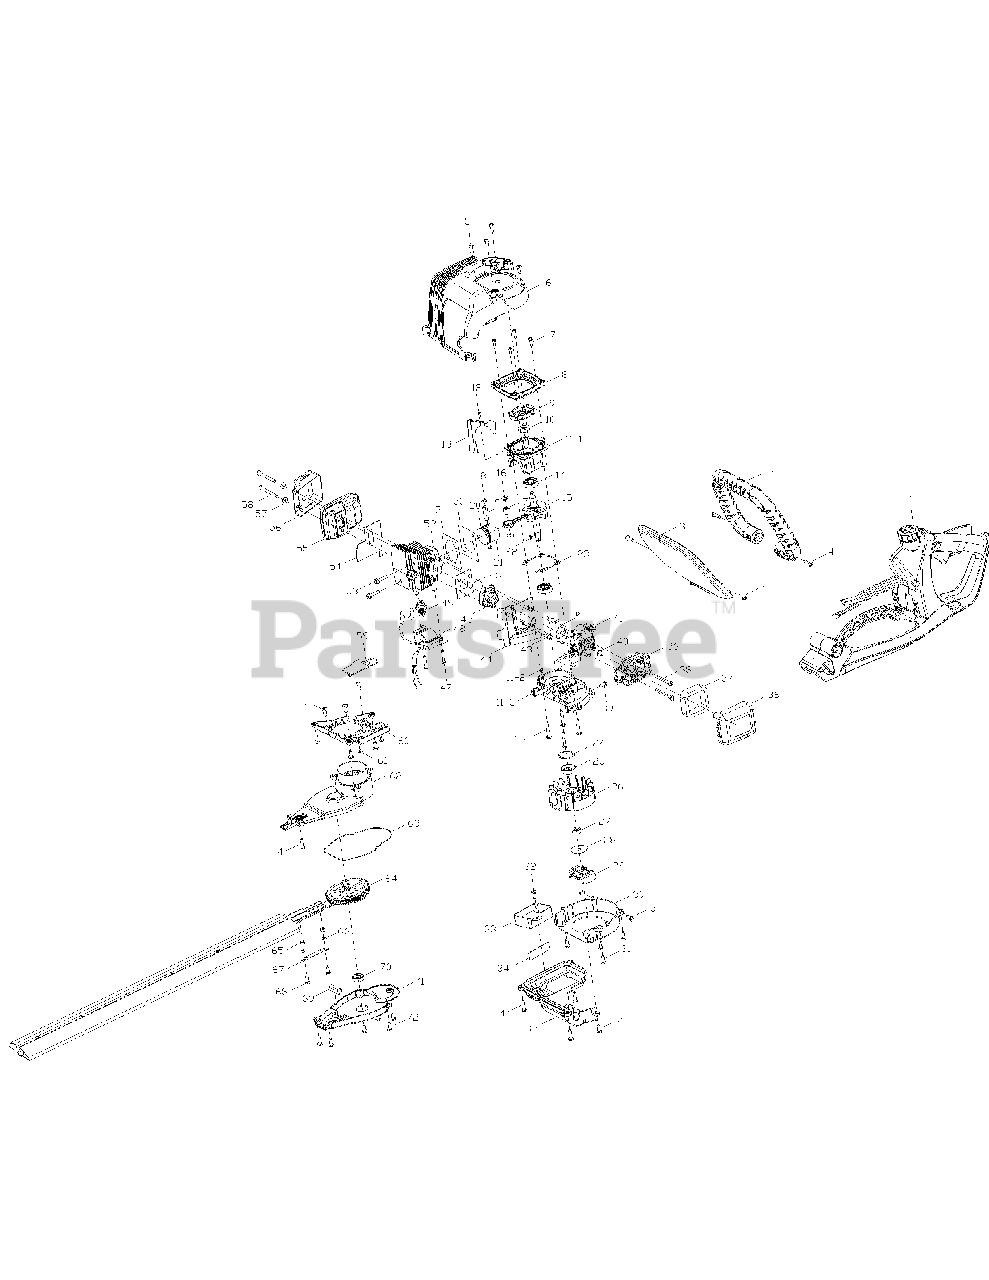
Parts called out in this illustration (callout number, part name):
1	HOUSING ASS'Y
6	STARTER HOUSING ASS'Y
8	CONNECT CASE
11	CRANK CASE ASS'Y
11-1	CRANK CASE (STARTER)
11-3	CRANK CASE (FLYWHEEL)
13	BAFFLE CYLINDER
14	BALL BEARING
15	CRANK ASS'Y
16	SPACER, PISTON
17	NEEDLE BEARING
20	PISTON RING
22	KEY (FLYWHEEL)
23	CRANK CASE GASKET
24	C-CLIP
30	CRANK CASE COVER
35	ENGINE COVER
36	AIR CLEANER ASS'Y
37	FILTER AIR
40	O-RING (AIR)
41	CARBURETOR
42	GASKET (CARBURETOR)
45	INSULATOR
46	GASKET (INSULATOR)
48	IGNITION ASS'Y
50	GASKET CYLINDER
51	GASKET CYLINDER
54	GASKET MUFFLER
55	MUFFLER ASS'Y
62	BRAKE ASS'Y
64	GEAR ASS'Y
67	STEEL BOARD
